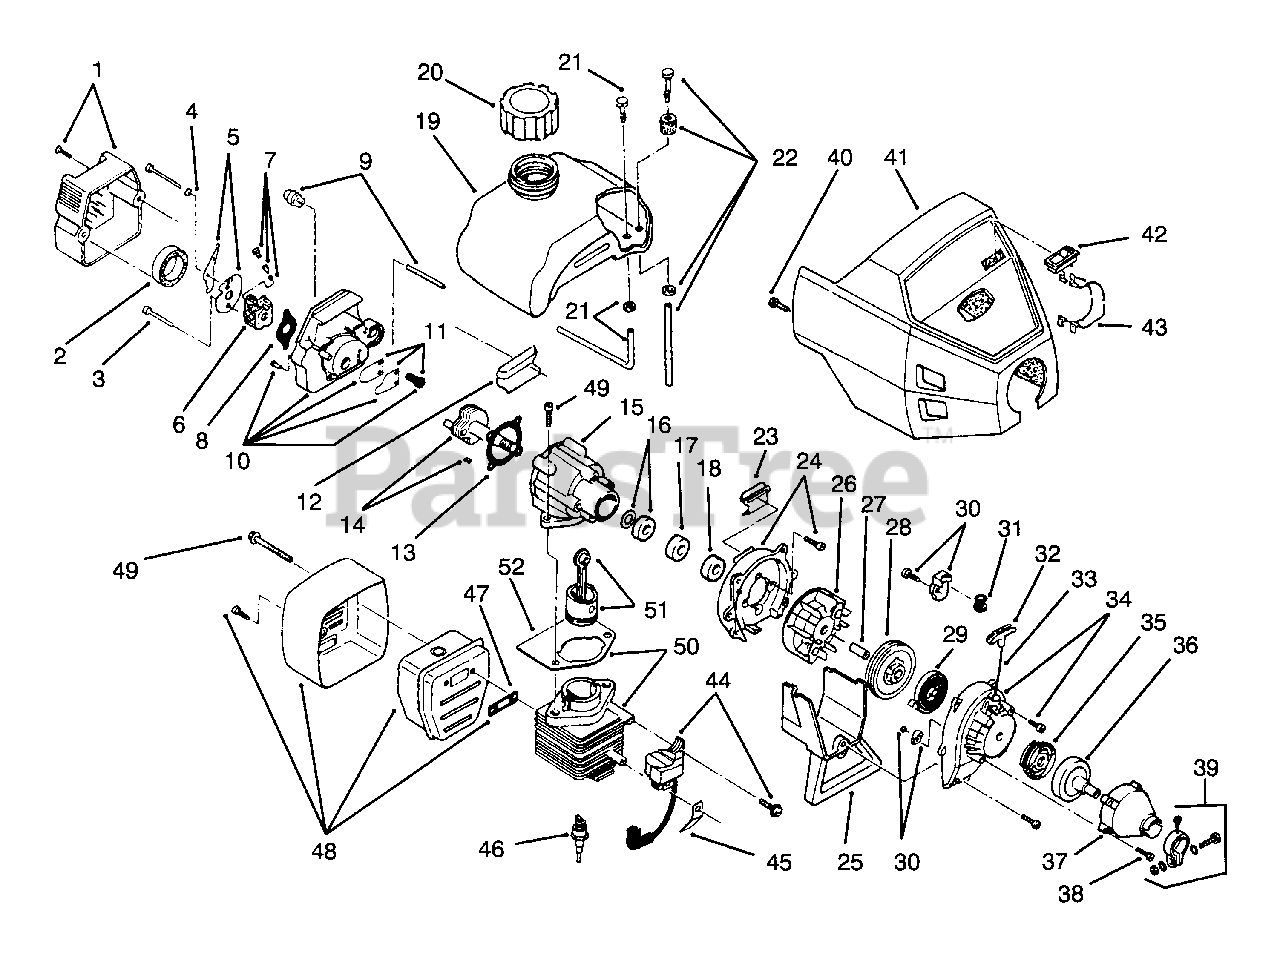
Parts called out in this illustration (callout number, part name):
1	Assy.-Carburetor/Air Clean (Inc. Ref. No. 2)
2	Filter-Air Cleaner
3	Screw-Carburetor
4	Washer-Wave
5	Choke-Lever and Plate
6	Assembly-Carburetor
7	Throttle Adj.-Walbro
8	Gasket-Carb. (10 Pack)
9	Assy.-Primer and Hose
10	Assembly-Carb. Mount (Incl. Ref. No. 11 & 13)
11	Assembly-Reed
12	Pad-Mounting, Rear
13	Gasket (10 Pack)
14	Assembly-Power Shaft
15	Assy.-Crankcase (Incl. Ref. No. 14-18)
16	Assembly-Inner Bearing
18	Assembly-Outer Bearing
19	Assembly-Fuel Tank (Incl. Ref. No .20-22)
20	Assembly-Fuel Cap
21	Assembly-Return Line
22	Assembly-Fuel Line
23	Pad-Mounting, Front
24	Assembly-Shroud
25	Shroud Extension & Stand
26	Assembly-Flywheel
28	Assembly-Recoil Pulley
29	Spring-Recoil
30	Assembly-Pulley Retainer
31	Guide-Rope
32	Handle-Pull
34	Assembly-Starter Housing
35	Assembly-Clutch Rotor
36	Assembly-Clutch Drum
37	Assembly-Clutch Cover
38	Screw-Clutch Cover
39	Assembly-Clamp
40	Screws-Engine Cover
41	Assembly-Engine Cover
43	Assembly-Lead Wire
44	Assembly-Module
45	Tab-Ground
46	Spark Plug
47	Gasket-Exhaust (10 Pack)
48	Assembly-Muffler
49	Bolt-Muffler
50	Assembly-Cylinder (Incl. Ref. No. 52)
51	Assy. Piston & Rod
52	Gasket-Cylinder
